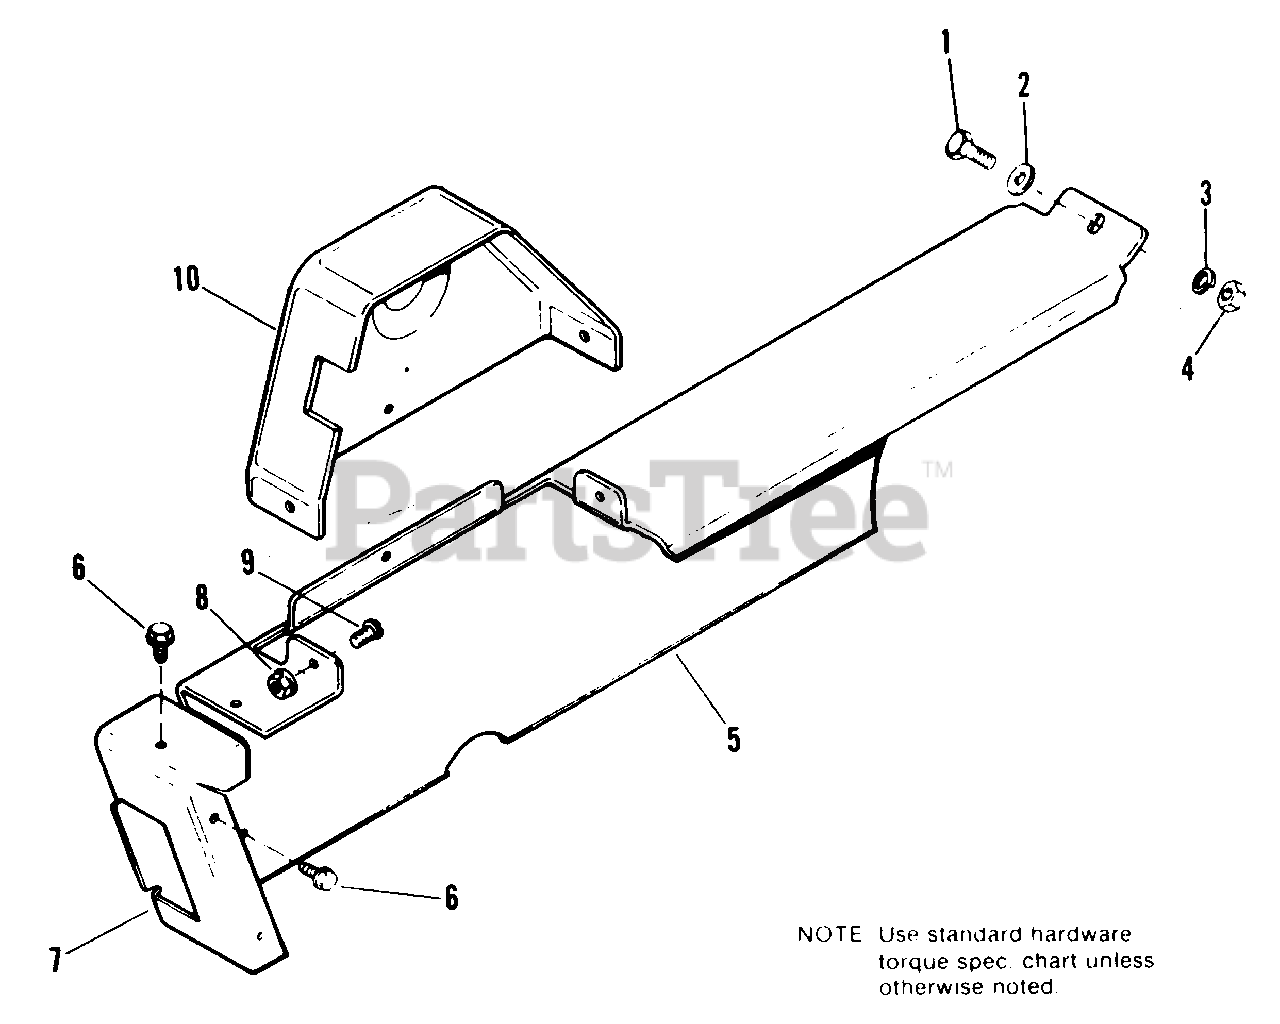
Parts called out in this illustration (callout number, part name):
1	CAPSCREW, Hex Hd., 1/4-20 x 1/2
2	WASHER, Plain, 1/4
3	LOCKWASHER, 1/4
4	NUT, Hex, Full, 1/4-20
5	COVER ASSY., Belt, Lower
6	SCREW, Hex, Taptite, 1/4-20 x 3/8
7	SUPPORT, Belt Cover
8	NUT, Hex, Flange, Whizlock, 1/4-20
9	SCREW, Rd. Hd., 1/4-20 x 1/2
10	COVER ASSY., Belt, Top
